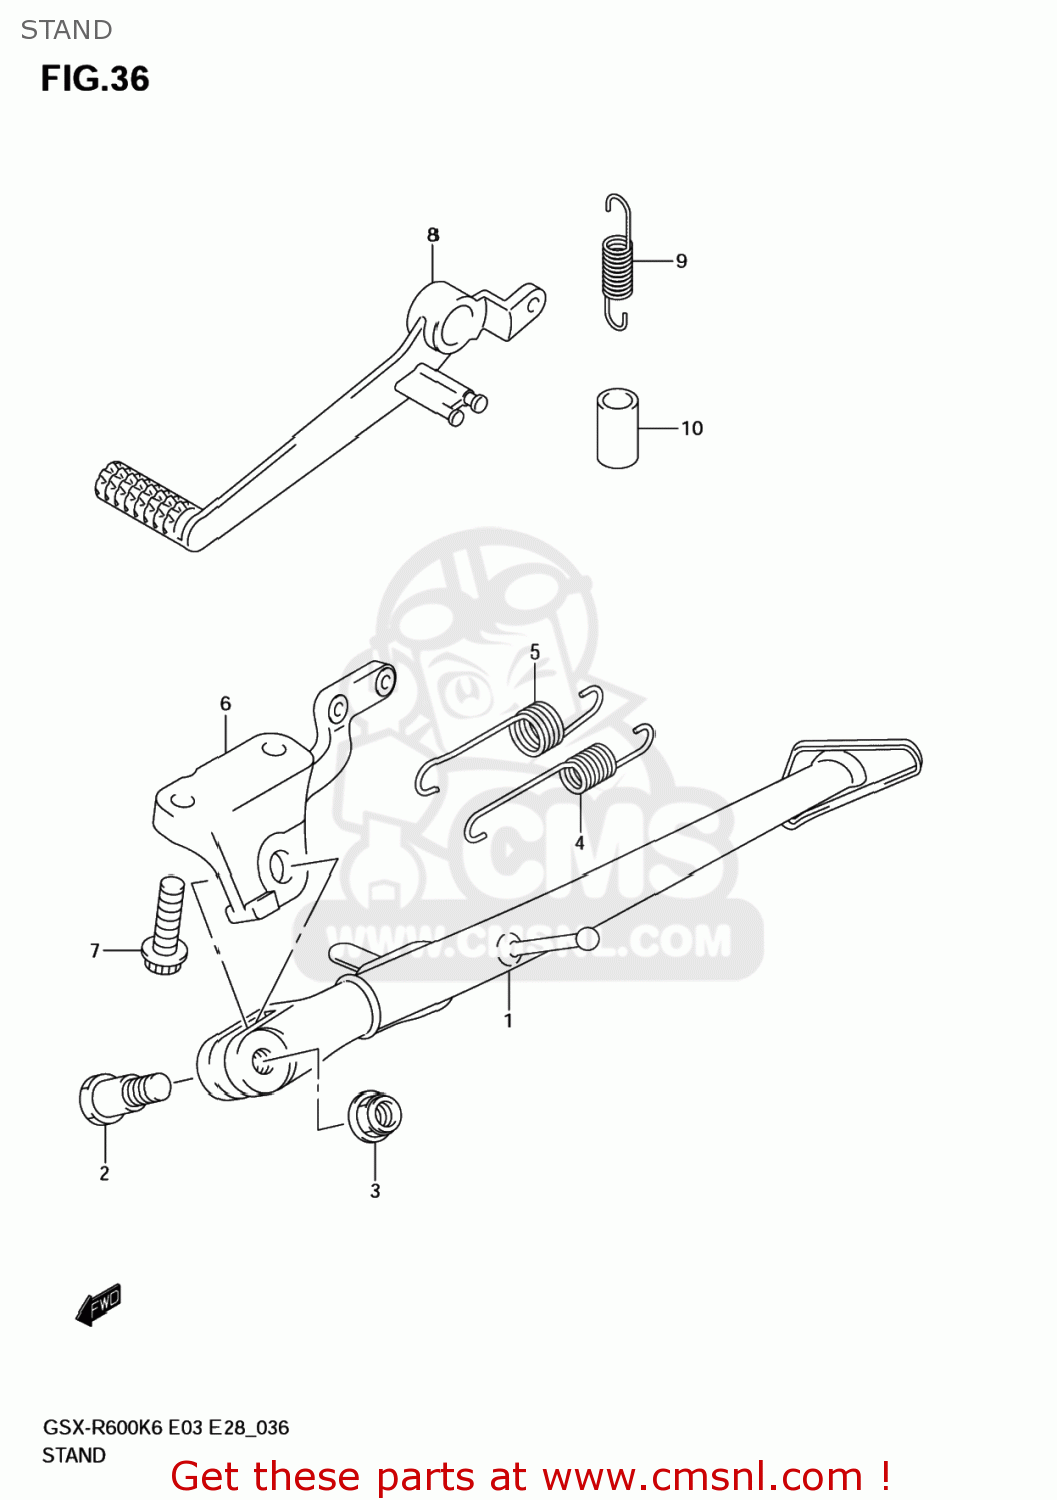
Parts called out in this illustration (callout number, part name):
1	STAND,PROP
2	BOLT(10X21)
3	NUT
4	SPRING, INNER
5	SPRING
6	BRACKET,PROP STAND
7	BOLT (10X28)
8	PEDAL,BRAKE
9	SPRING
10	HOSE(11X15X600)
